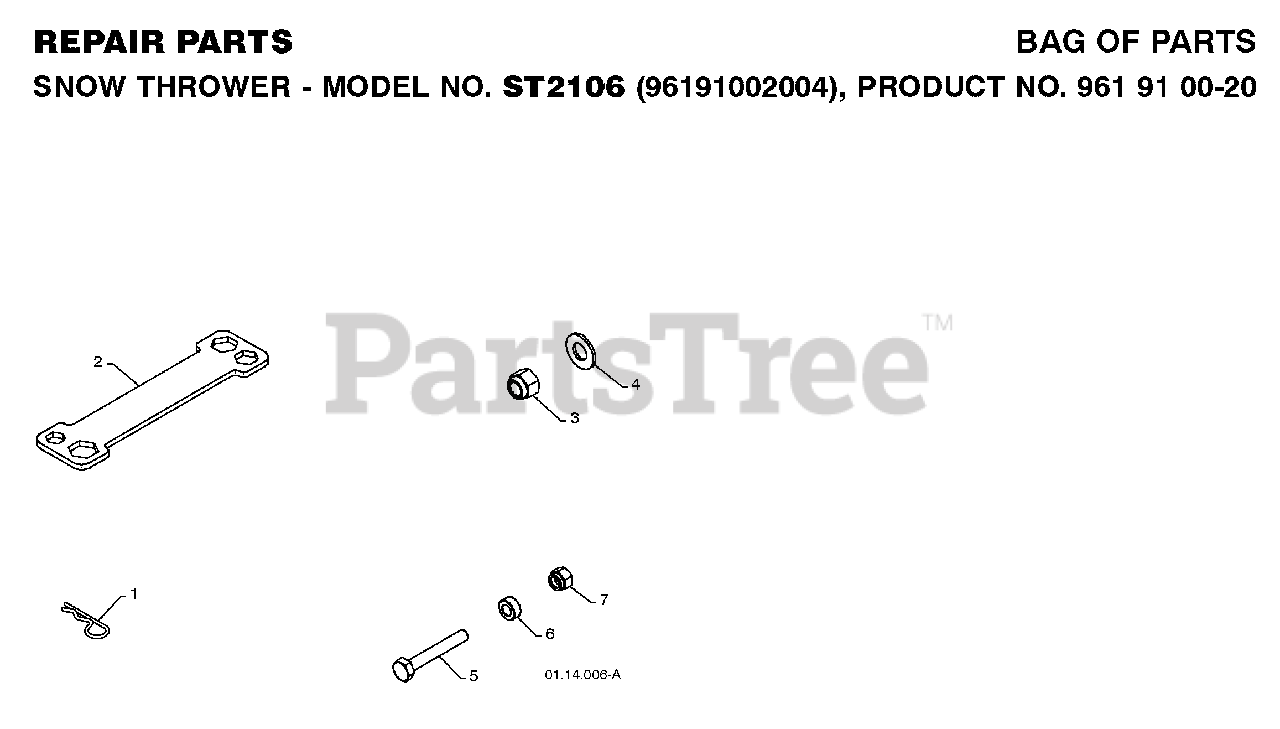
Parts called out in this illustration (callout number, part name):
1	SPRING RETAINER
2	RP WRENCH, SNOWTHROWER
3	NUT
5	BOLT, SHEAR
7	LOCKNUT
